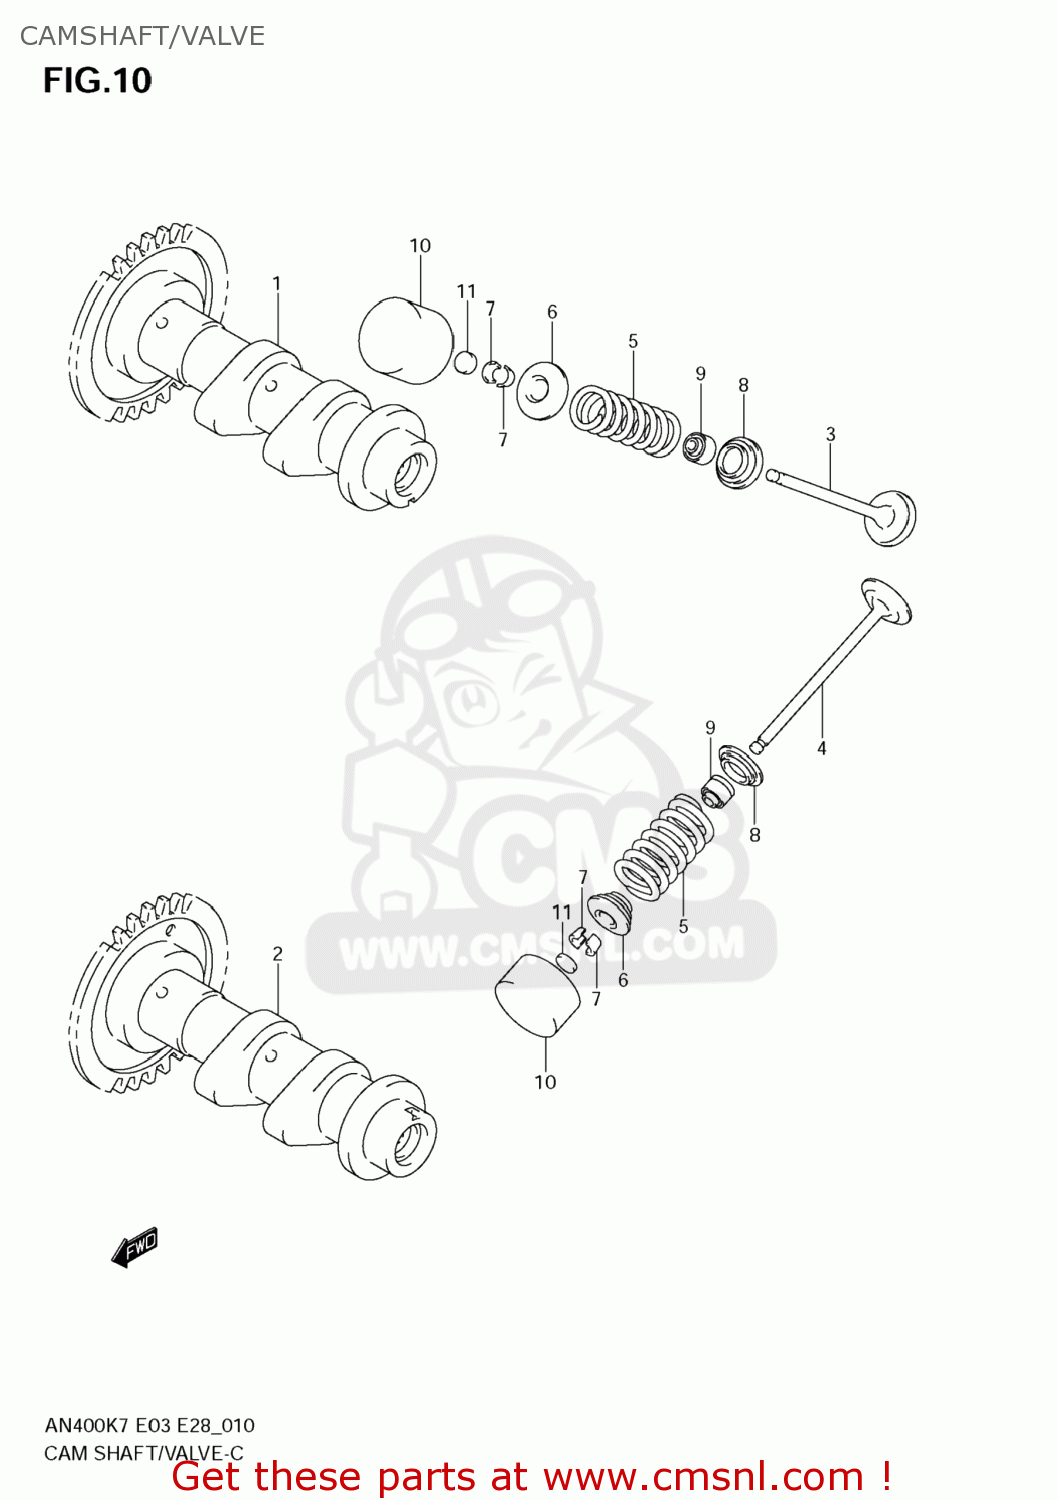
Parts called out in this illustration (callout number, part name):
1	CAMSHAFT,INTAKE
2	CAMSHAFT,EXHAUST
3	VALVE,INTAKE
4	VALVE,EXHAUST
5	SPRING,VALVE
6	RETAINER,VALVE SPRING
7	COTTER VALVE
8	SEAT,VALVE SPRING
9	SEAL,OIL(4.5X10X8)
10	TAPPET
11	SHIM,TAPPET
12	SHIM SET,TAPPET
13	CASE,TAPPET SHIM
